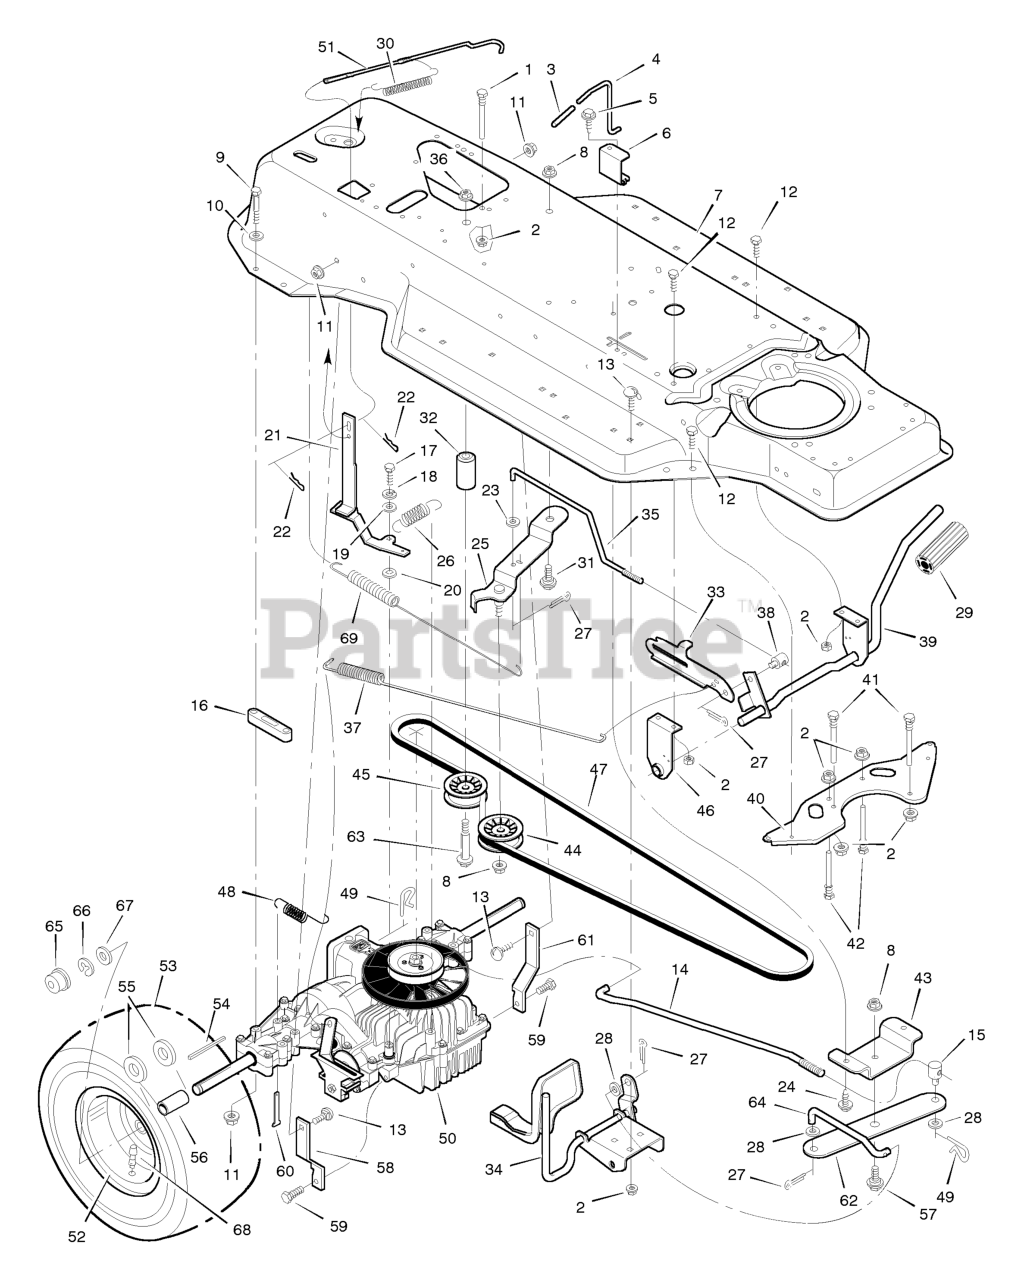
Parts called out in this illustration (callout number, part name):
1	Guide, Belt
2	Nut, Flange
4	Rod, Parking Brake
6	Bracket, Guide
7	Frame Assembly
8	Nut, Flange
9	Bolt
10	Washer
11	Nut, Flange
13	Bolt, Carriage
14	Rod, Secondary Control
15	NUT, Adjusting, 1/2-13
16	Spacer, Hydro
18	Lockwasher
21	Lever, Control
22	Hair Pin
23	Washer
25	Idler Mount Assembly
26	Spring, Extension
27	Cotter Pin
29	Pedal
30	Spring, Extension
31	Shoulder Bolt
32	Spacer
33	Latch, Parking Brake
34	Pedal Assembly
35	Clutch Rod
36	Nut, Flange
37	Spring, Extension
38	Nut, Adjusting
39	Pedal Lever Assembly
40	Plate, Belt Guide
41	Screw, Guide
42	Screw, Guide
43	Support, Pivot Bracket
44	Idler Pulley
45	Idler Pulley
46	Support, Pedal
47	V- Belt
48	Spring, Extension
49	Hair Pin
50	Transaxle **
51	Rod, Dump Valve
52	Wheel & Tire Assembly
53	Tire *
54	Square Key
56	Spacer, Wheel
57	Shoulder Bolt
58	Strap, Torque (Right)
60	Clip, Brake
61	Strap, Torque (Left)
62	Bracket, Pivot
63	Shoulder Bolt
64	Rod, Primary Control
65	Hub Cap
66	E- Ring
68	Valve Stem
69	Spring, Extension
